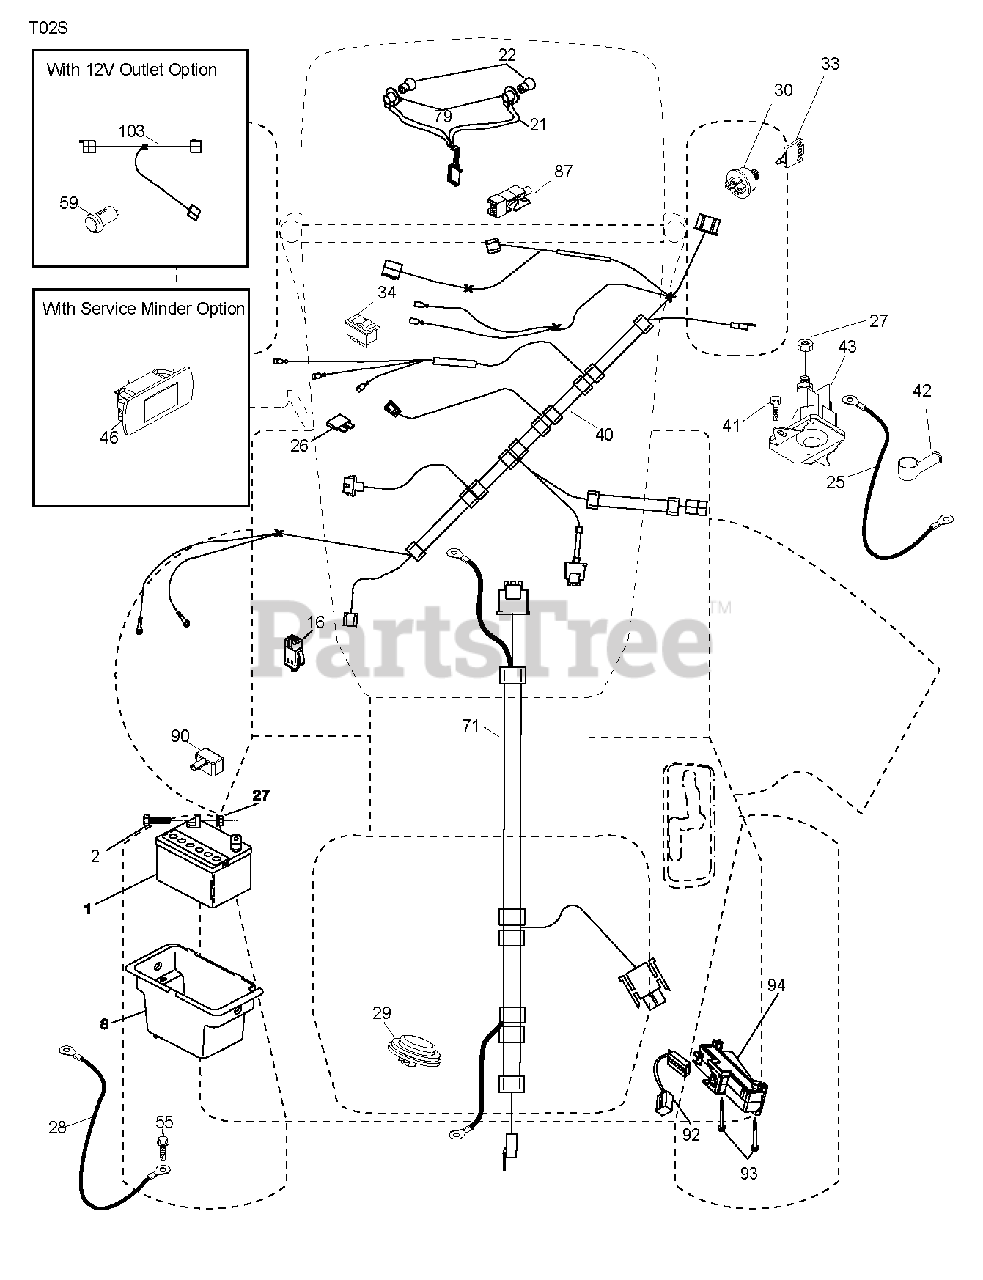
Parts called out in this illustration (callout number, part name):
1	Battery, Dry 30 Amp
2	BOLT.HEX.1/4.X.3/4.DICHROMATE
8	BOX.BATTERY.MNT.REAR.L
16	SWITCH INTERLOOK PUSH-IN
21	HARNESS.LIGHT W/4152J BULBS
25	CABLE.STARTER.6GA.BL/RED.14.
26	FUSE 20AMP
27	NUT
28	CABLE.BLACK.18"REAR.BA
29	SWITCH.SEAT.DELTA.OPC.
30	SWITCH.IGN.DELTA.W.LGH.ROS
33	KEY.CHAIN.BLISTER.PACK.GEN.USA
40	HARNESS IGN. DASH
41	SCREW
42	TERMINAL COVER
43	SOLENOID.W/BRASS.PLUNGER
46	RP GUAGE.SRVCMNDR.HRMTR.
55	SCREW 5/16"
71	HARNESS.IGN.CHASS.TEX.REAR.BAT
79	BULB HOLDER ASM.
87	SWITCH.INTRLCK.CLUTCH.
90	COVER.TERMINAL.BATTERY
92	HARNESS.PIGTAIL.CONSLE
93	SCREW.PLASTITE
94	MODULE.REVERSE.ROS
